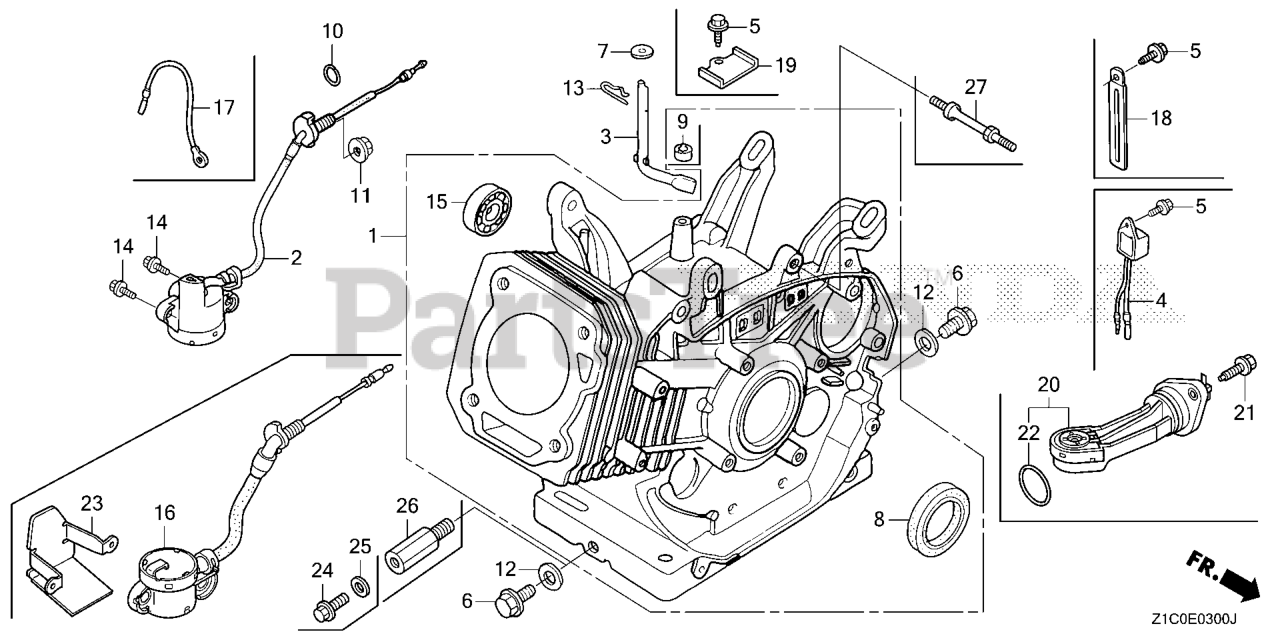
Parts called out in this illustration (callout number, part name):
1	CYLINDER ASSY.
3	SHAFT, GOVERNOR ARM
7	WASHER (8.2X17X0.8)
8	OIL SEAL (35X52X8) (NOK)
9	OIL SEAL (8X14X5)
10	O-RING (14MM) (ARAI) Use up to Engine SN 2949254.
11	NUT, FLANGE (10MM)
13	PIN, LOCK (10MM)
14	BOLT, FLANGE (6X12) Use up to Engine SN 1543277.
15	BEARING, RADIAL BALL (6202)
16	SWITCH ASSY., OIL LEVEL
24	BOLT, DRAIN PLUG
25	WASHER, DRAIN PLUG (12MM)
